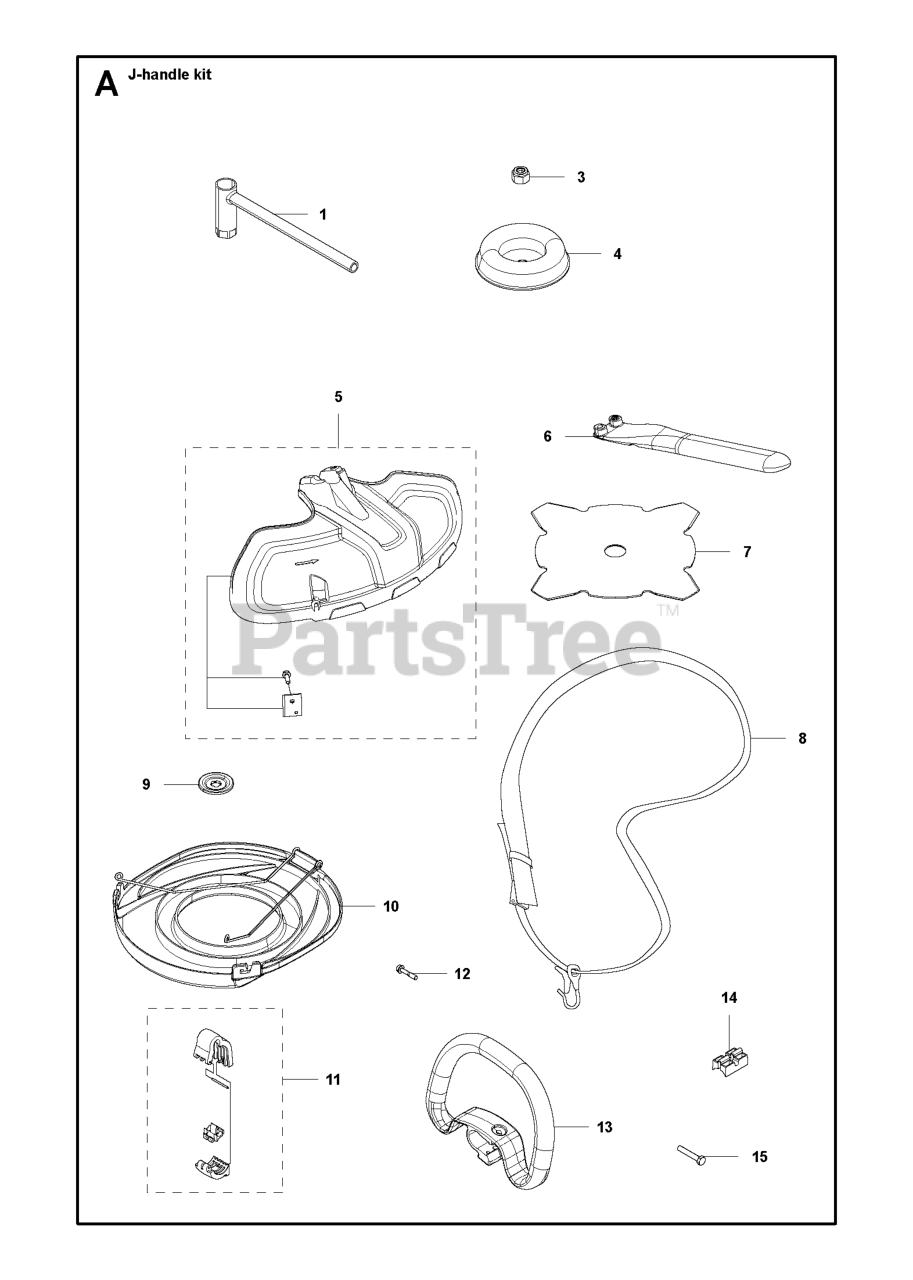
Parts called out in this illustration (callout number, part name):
1	COMBI WRENCH
3	GEARHEAD NUT - BRUSHCUTTER
4	SUPPORTING CUP
5	COMBINATION GUARD
7	Blade - Grass
8	Harness - Diagonal with sign
8	Harness-w/o warning
9	SUPPORT FLANGE
10	BLADE GUARD TRANSPORT
11	HANGING BRACKET
12	SCREW IHSCFTO
13	HANDLE
14	SPACER PLASTIC
15	BOLT FLANGE
